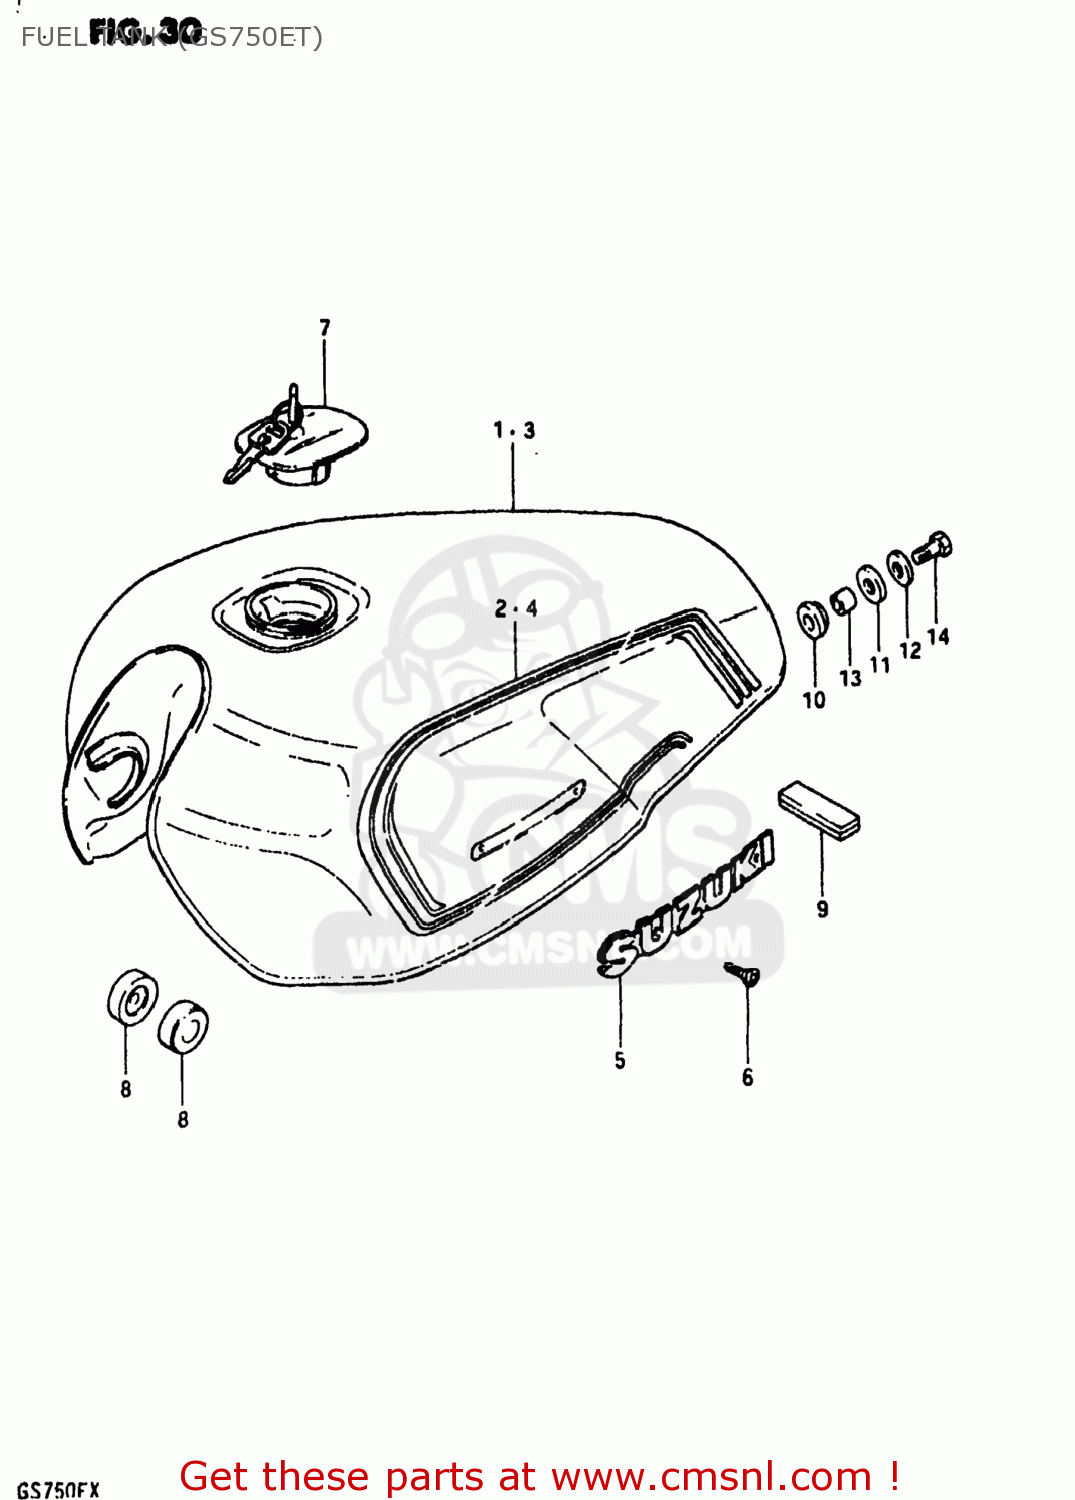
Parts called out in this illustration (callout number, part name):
1	TANK ASSEMBLY,FUEL
2	TAPE SET,FUEL TANK
3	TANK ASSEMBLY,FUEL
4	TAPE SET,FUEL TANK
5	EMBLEM,FUEL TANK
6	SCREW 3X6
7	CAP SET,FUEL TANK
8	CUSHION
9	CUSHION
10	CUSHION
11	CUSHION
12	WASHER (8.5X29X1.6)
13	SPACER(8.5X12X19)
14	BOLT (8X30)
